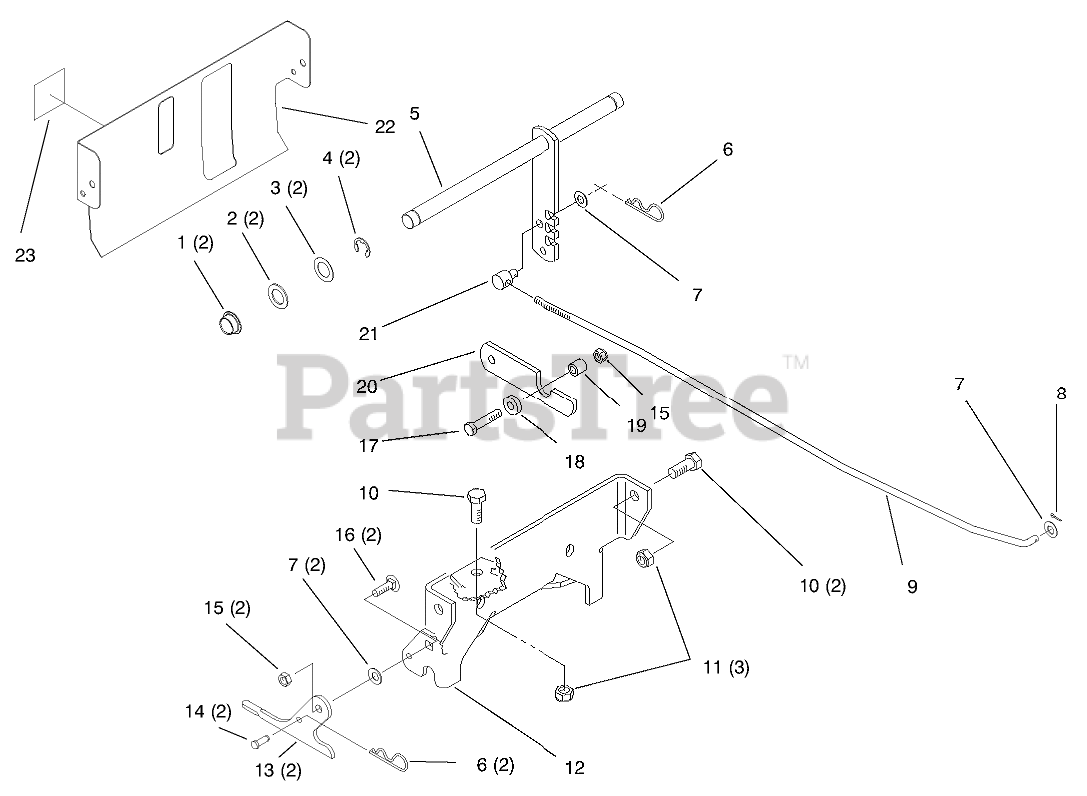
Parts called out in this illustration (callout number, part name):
1	BUSHING-BRONZE
2	WASHER
3	WASHER-SHIM
4	E-RING
5	LEVER ASM
6	PIN-HAIR
7	WASHER-FLAT
8	PIN-COTTER
9	ROD-LIFT
10	SCREW-HH
11	NUT-LOCK, NI
12	BRACKET-MOUNTING
13	PLATE-LATCHING
14	PIN-CLEVIS
15	NUT-LOCK, NI
16	BOLT-CARR
17	SCREW-HH
18	Washer
19	SPACER
20	CATCH-SPRING
21	TRUNNION-CLUTCH ROD
22	COVER-REAR
23	DECAL-LEVEL, FUEL
